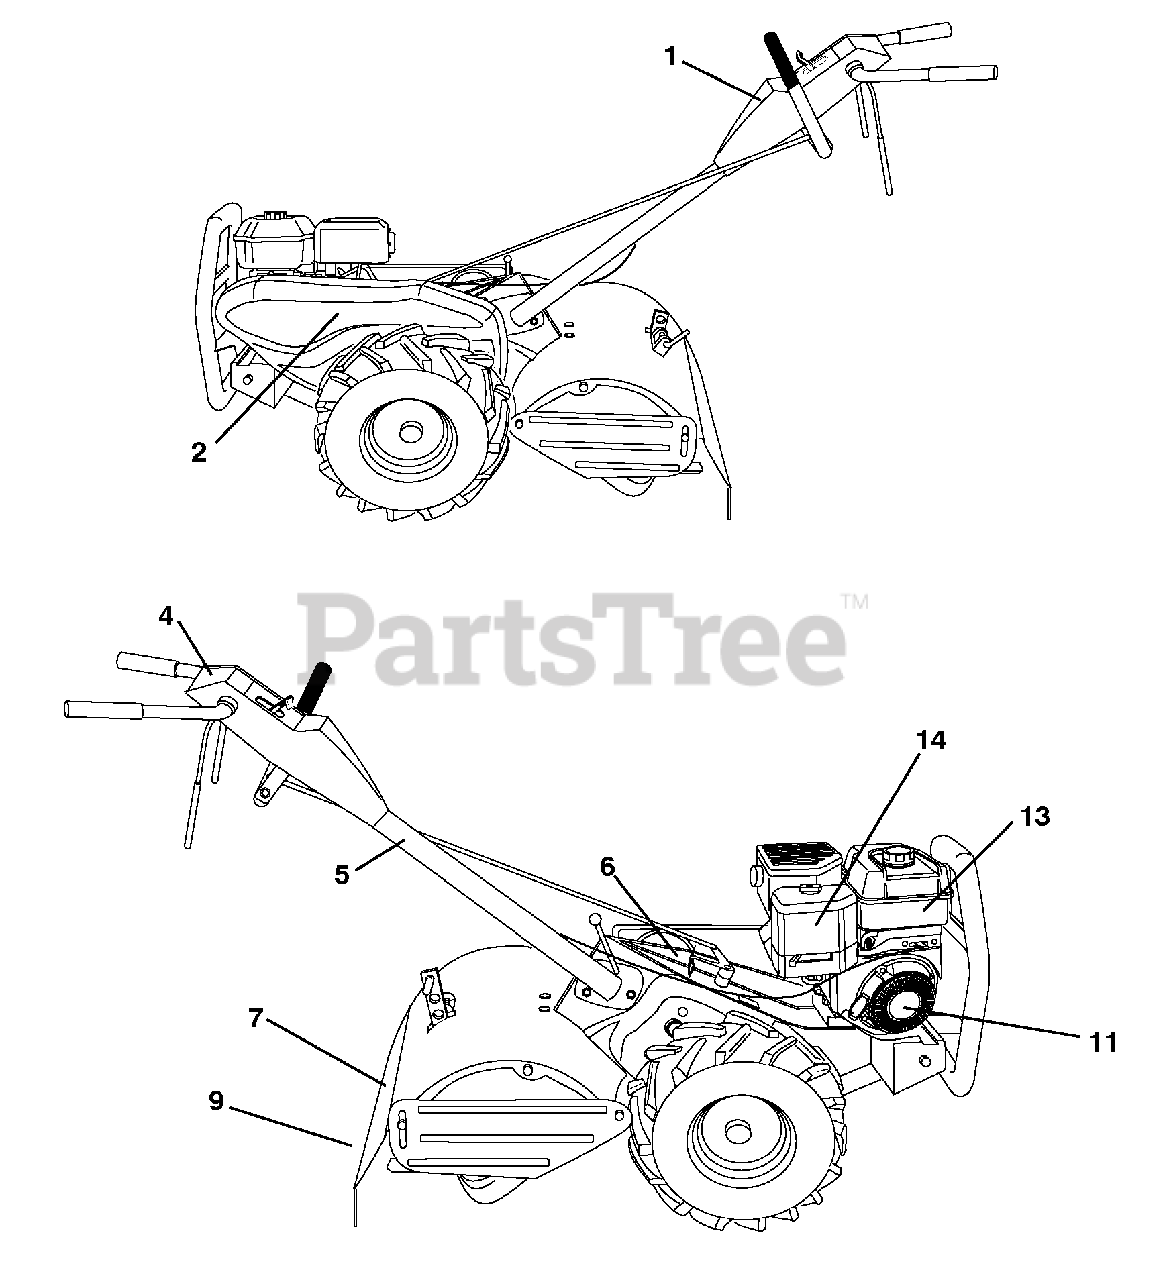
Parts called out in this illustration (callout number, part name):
1	Decal, CNTRL PNL
2	Decal, Decal, Blt Grd
4	Decal, Instruction, Tilling
5	Decal, Hand Placement
6	Decal, Shift Indicator
7	Decal, Caution
9	Decal, Warning, Rotating Tines
11	Decal, Rewind
13	Decal, B&S Tank
14	Decal, B&S, Air Cleaner
14	Manual, Operator's, English/French
14	Manual, Repair Parts, English/French
